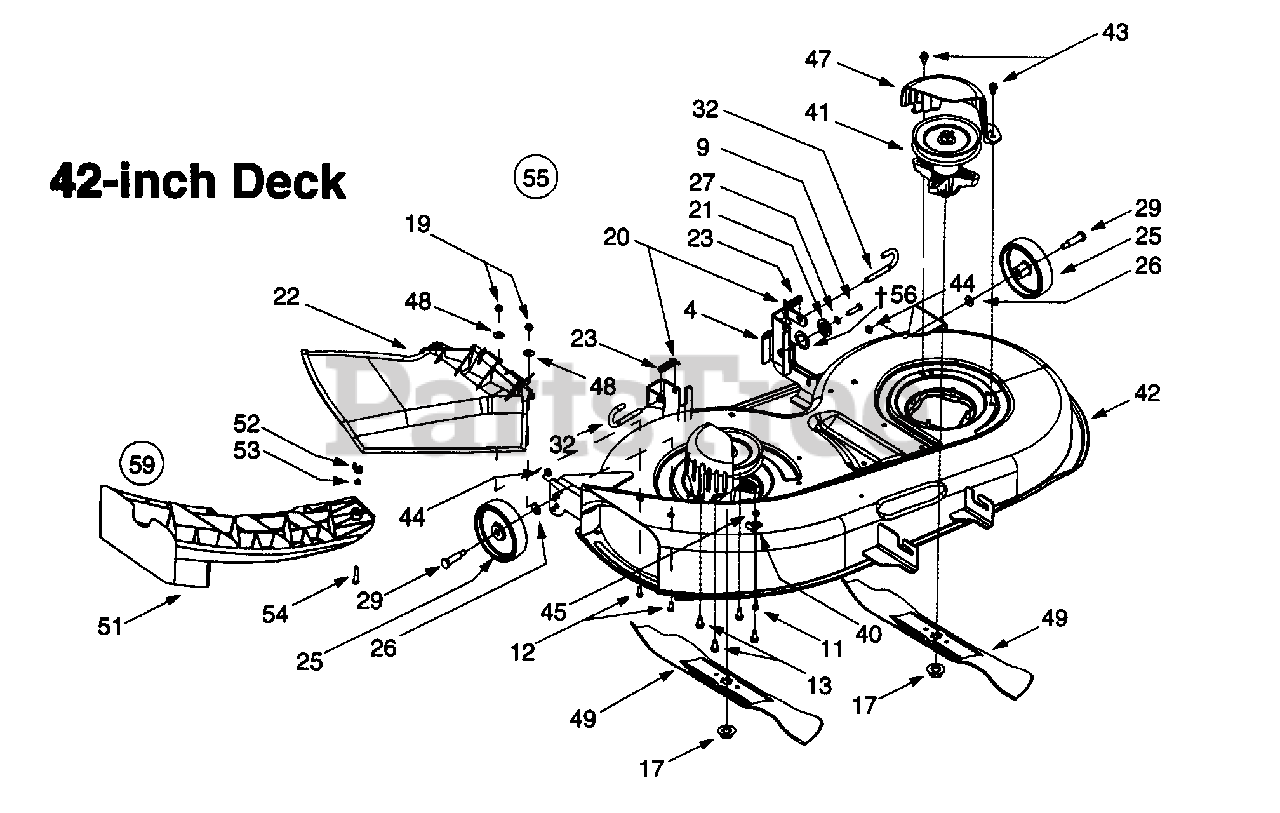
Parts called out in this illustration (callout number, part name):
9	Hex Cap Screw, 5/16-18 x 1.25
11	Self Tapping Screw, 5/16-18 x .875
12	Hex Cap Screw, 1/4-20 x .62
13	Self Tapping Screw, 5/16-18 x .75
17	Hex Flange Nut, 5/8-18
19	Hex Flange Lock Nut, 1/4-20
20	Internal Cotter Pin, .072 x 1.12
21	Deck Adjustment Gear
22	Side Discharge Chute Assembly
23	Compression Spring, .406 x .531 x 1.75
25	Deck Wheel, 5 x 1.38
26	Bell Washer, .401 x .87 x .063
27	Lock Washer, 5/16
29	Shoulder Spacer, .498 x 1.53
32	Deck Release Pin
40	Retainer Hook
41	Spindle Assembly, 5.75 Dia
43	Self Tapping Screw, 5/16-18 x .625
44	Top Lock Jam Nut, 3/8-16
45	Hex Sems Nut, 1/4-20
47	Belt Cover
48	Bell Washer, .265 x .75 x .062
49	Three-in-one Blade, Star Center, 21.23 42
51	Mulch Plug, 42-inch Decks
52	Wing Nut, 1/4-20
53	Center Lock Nut, 1/4-20
54	Hex Cap Screw, 1/4-20 x 1.25
59	Mulch Kit, 42-inch Decks
